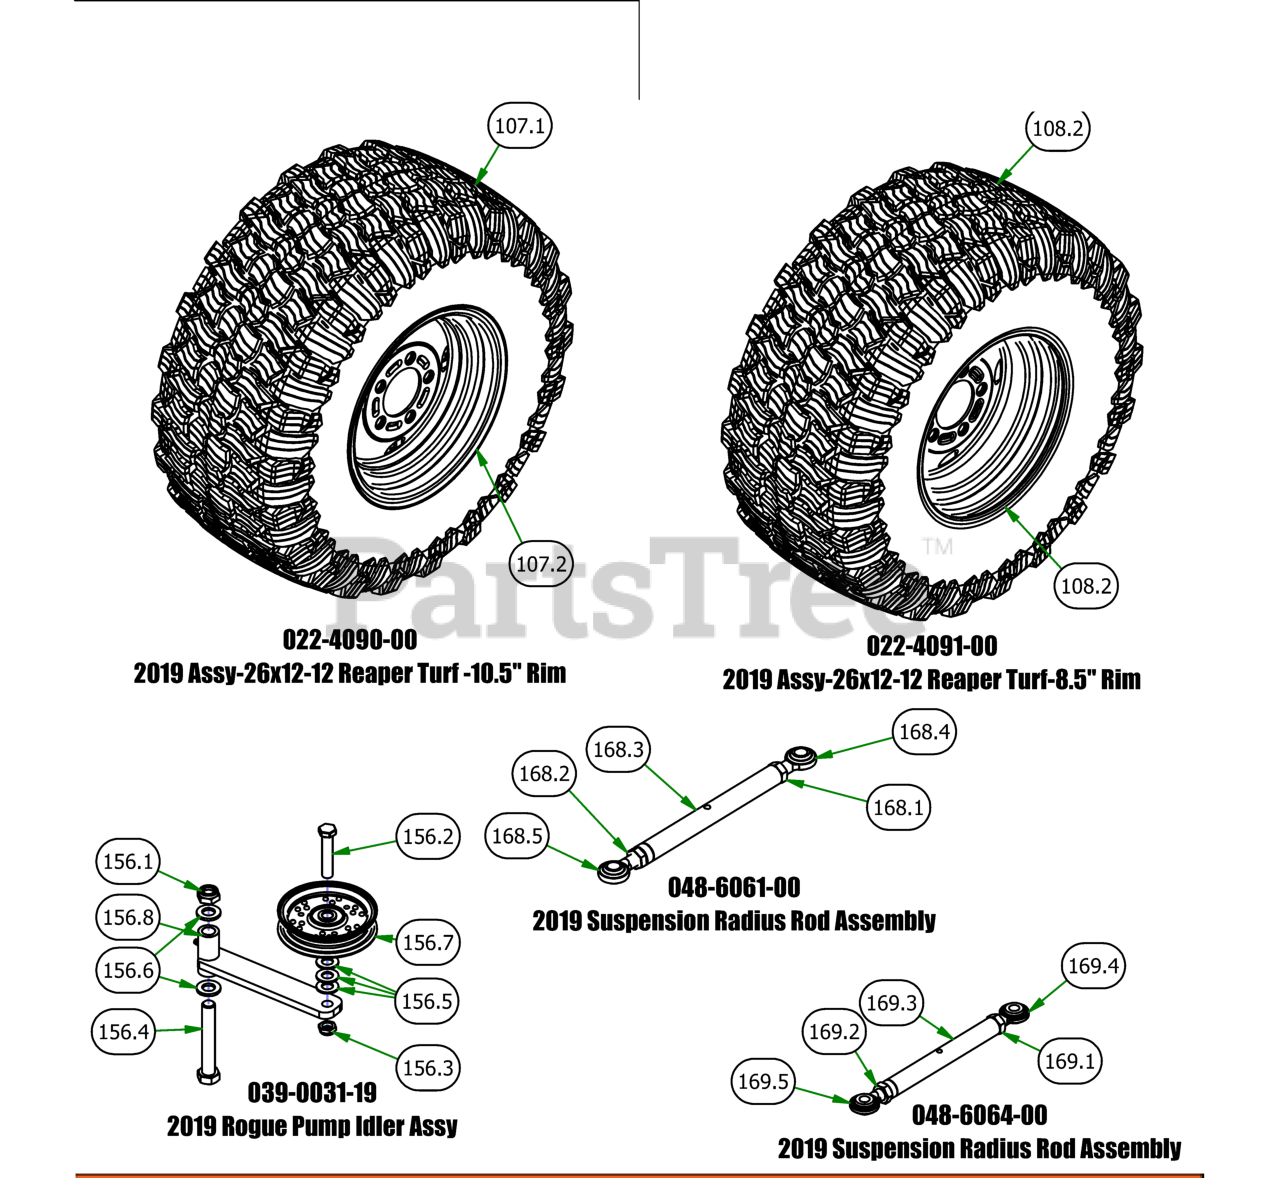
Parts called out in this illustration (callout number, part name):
107.1	2019 26x12-12 Reaper Turf Tire
107.2	2019 10.5" Wheel
108.1	12x8.5 Black Wheel
108.2	2019 26x12-12 Reaper Turf Tire
156.1	5/8-11 Nylon Insert Jam Half Nut
156.2	1/2" x 3" Hex Bolt
156.3	1/2" Nylcock Nut (1/2 Jam)
156.4	5/8" x 4" Hex Bolt
156.5	1/2" Washer (Grade 8)
156.6	.630 ID Plastic Washer
156.7	4 3/4 Idler Pulley - ABFI-76
156.8	2019 Vertical Suspension Drive Tensioner
168.1	5/8-11 HEX JAM NUT ZINC
168.2	NUT, 5/8-18LH
168.3	2019 Suspension Link Body
168.4	2019 RH 5/8" Heim
168.5	2019 LH 5/8" Heim
169.1	3/4-16 HEX JAM NUT ZINC
169.2	3/4-16 LH HEX JAM NUT ZINC
169.3	Rear Radius Rod, 3/4 Body
169.4	3/4-16 x 5/8 RH Heim
169.5	3/4-16 x 5/8 LH Heim
